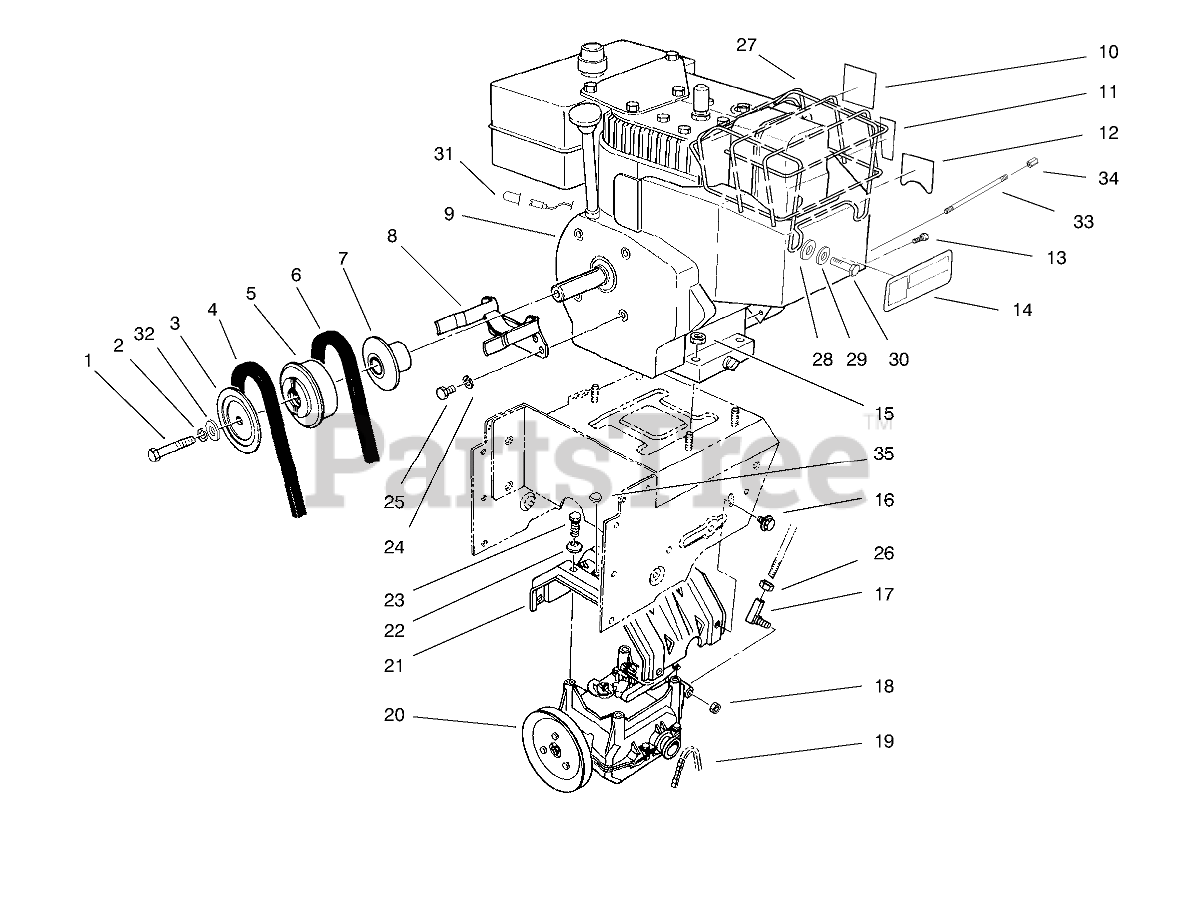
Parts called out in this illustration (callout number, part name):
1	SCREW-HH
2	WASHER-LOCK
3	SHEAVE-HALF, IMPELLER
4	V-BELT
5	PULLEY-ENGINE, CENTER
6	V-BELT-TRACTION
7	SHEAVE-HALF, TRACTION
8	Guide-Belt
9	Engine
10	DECAL - PRIMER
11	DECAL-THROTTLE
12	DECAL-CHOKE
13	SCREW-HWH
14	DECAL-SURFACE, HOT
14	DECAL-WARNING, HOT SURFACE
15	NUT-HF
16	SCREW-HHF
17	BALL-JOINT
18	NUT-LOCK
19	CHAIN
20	TRACTION GEARCASE ASM
21	Frame-Transmission
22	WASHER-SPRING
23	SCREW-HWHTF
24	WASHER-LOCK
25	SCREW-HH
26	NUT-HJ
27	Guard-Muffler
28	Washer-Flat
29	Washer-Lock
30	Screw
31	CAP-WIRE, LITE
32	WASHER
32	WASHER-FLAT
33	NIPPLE-PIPE
34	CAP-PIPE
35	CAP-PLUG
